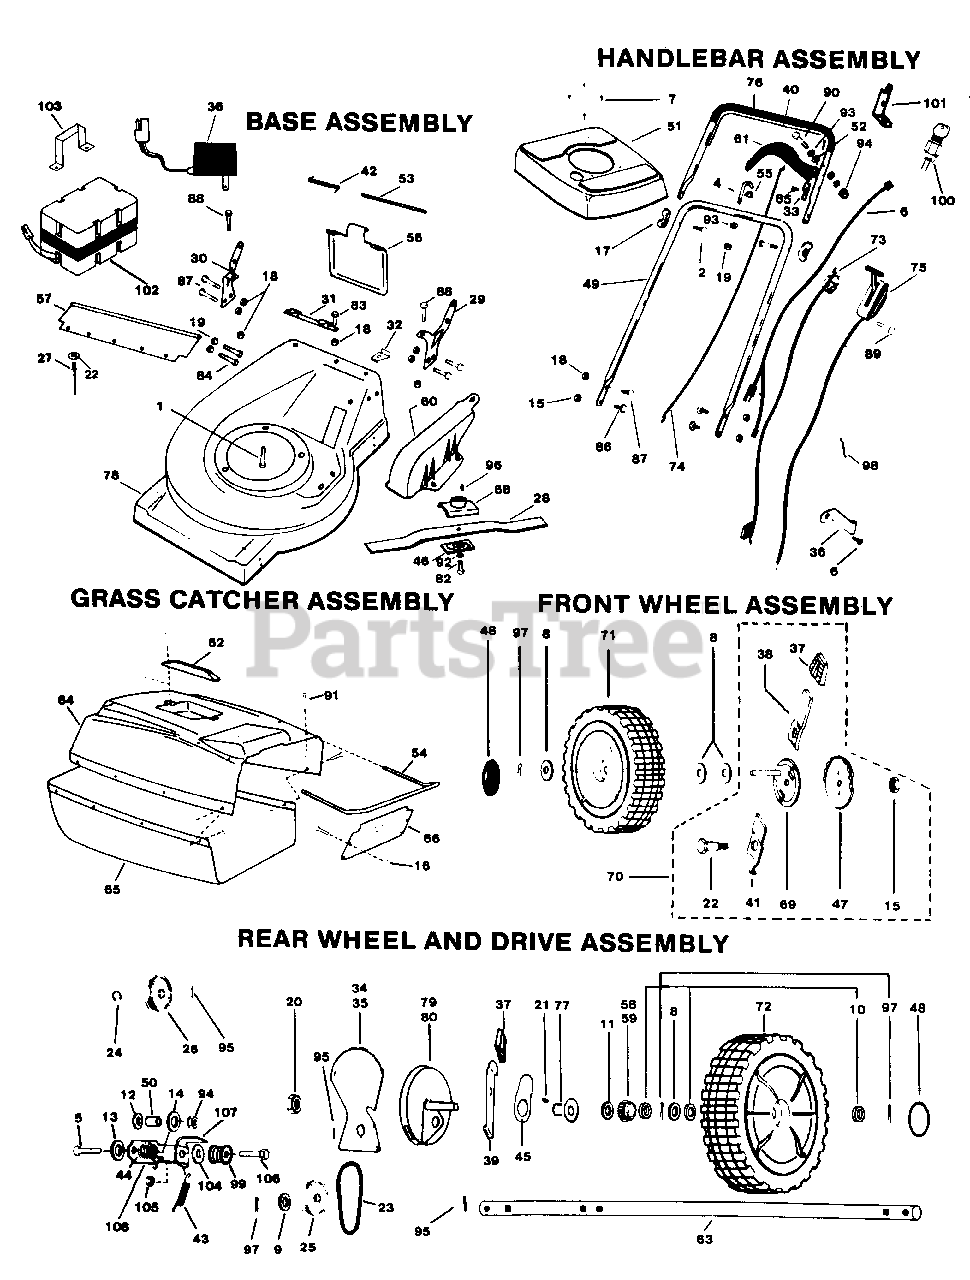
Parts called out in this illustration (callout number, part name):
1	Screw .375-16 x 1.00 Ind. Hex Hd.
2	Saddle Bolt .312-18 x .750
3	Screw .250-20 x .750
5	Screw .250-20 x 1.250
6	Starter Cable Assembly
7	Screws-Engine Shroud
15	Nut .375-16 Keps
16	Nut #10-32 Keps
18	Nut .312-18 Keps
19	Nut .250-20 Keps
21	Key-Drive
22	Shoulder Bolt .375-16 x 1.00
24	Retaining Ring
25	Driven Pulley
26	Drive Pulley
27	Pop Rivet
28	Blade-21"
29	Lug-Handle-LH.
30	Lug-Handle-RH.
31	Attaching Bracket
32	Brkt.-Attaching
33	Brkt.-Bail Stop
34	Plate-Rear-RH.
35	Plate-Rear-LH.
36	Battery Charger
40	Bail Lever
42	Spring Door
43	Drive Spring
44	Idler Return Spring
46	Retainer Plate
49	Handle-Lower
50	Idler Bracket Bushing
51	Shroud-Engine
52	Spacer-Clutch Handle
53	Rear Door Hinge
54	Support Rod
55	Rope Guide
56	Rear Door
57	Drag Pan-20"
58	Drive Gear-L.H.
59	Drive Gear-R.H
60	Belt Cover
61	Clutch Handle
64	Top-Catcher
65	Bottom-Catcher
66	Back-Catcher
68	Blade Adaptor
69	Plate & Pin
70	Height Adj. Ass'y.
71	Wheel Ass'y.-8"
72	Wheel Ass'y.-10"
73	Zone Restart Cable
74	Traction Control Cable
75	Throttle Control
76	Handle-Upper
77	Support Hubs Brg. Ass'y.
79	Dust Cover-LH.
80	Dust Cover-RH.
81	Capscrew, Hex HD. .250-20 x .50
81	Decal-Start & Stop
81	Decal-Caution
81	Decal-Simplicity
82	Capscrew, Hex HD. .375-24 x 1.250
83	Bolt, Carriage .250-20 x .50
84	Bolt, Carriage .250-20 x .625
85	Screw #10-32 x .50
86	Capscrew, Hex HD. .375-16 x .750
87	Bolt, Carriage .312-18 x .750
88	Capscrew, Hex HD. .312-18 x .625
89	Capscrew, Hex HD. .250-20 x 2.00
90	Capscrew, Hex HD. .250-20 x 1.750
91	Screw #10-32 x .625
92	Lockwasher .375
93	Flatwasher .250
94	Nut, Lock .250-20
95	Roll Pin .187 x 1.00
96	Key, Woodruff.156 x .625
97	Pin, Cotter.125 x .750
98	Cable Tie
99	Idler Pulley Half
101	Switch Bracket
103	Battery Bracket
105	Locknut 3/8-16
106	Idler Bolt
107	Belt Guide Brk't
108	Idler Brk't
108	Decal-Engine Shroud
108	Decal-5 HP
108	Decal-21"
108	Decal-Clutch
108	Decal-Danger
